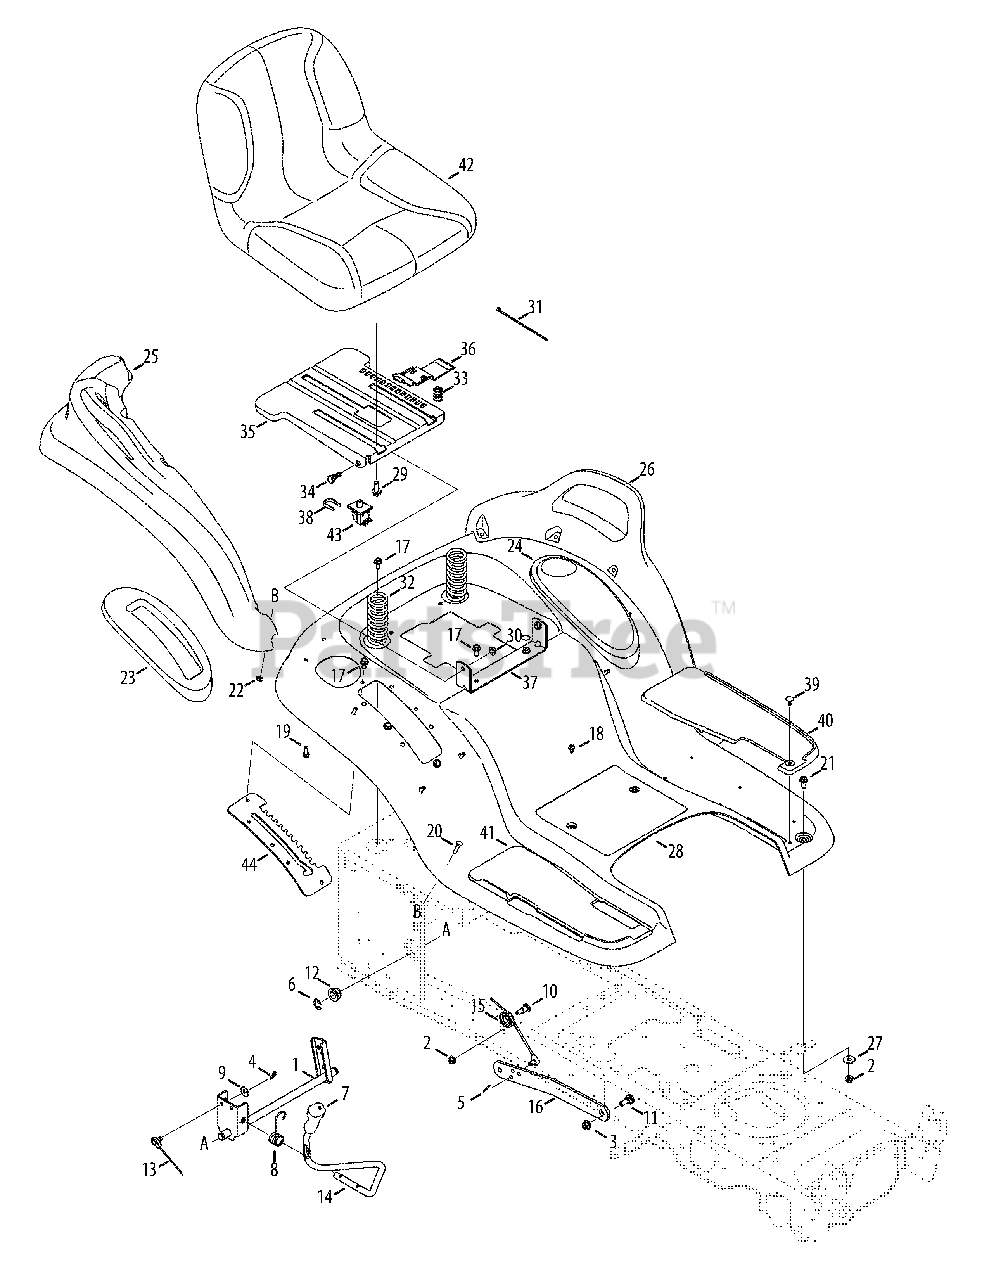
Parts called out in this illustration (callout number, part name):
1	Lift Shaft Assembly
2	Flangelock Nut, 5/16-18
3	Flangelock Nut, 3/8-16
4	Cotter Pin, .072 DIA. x 1.13 LG
5	Bow-Tie Cotter Pin
6	E-Ring, .625 DIA. SHAFT
7	Handle Grip
8	Torsion Spring
9	Spring Washer, .401 x .870 x .063
10	Shoulder Screw, .437 x .470:5/16-18
11	Shoulder Bolt, .500 x .270:3/8-16
12	Hex Flange Bearing
13	Lift Cable, 16.16 LG
14	Lift Handle
15	Pulley Roller Cable
17	Taptite Screw, Lock Washer, 5/16-18:.750
18	Taptite Screw, Lock Washer, 1/4-20
19	Hi-Lo Screw, Lock Washer, 1/4-15
20	Carriage Screw, 1/4-20:1.00
21	Taptite Screw, 5/16-18:.750
22	Sems Nut, 1/4-20
23	Lift Lever Cover
24	Cover with Cup Holder
25	RH Fender Flare
26	LH Fender Flare
27	Flat Washer, .344 x 1.00 x .063 HDN
29	Hex Head Flange, 3/8-16:.875
30	Flangelock Nut, 5/16-18
31	Cable Tie, 3/16 x .05 x 7.4
32	Compression Spring, 1.71 x 3.735 x .238
33	Compression Spring, .68 x 1.065 x .055
34	Shoulder Screw, .437 x .268:5/16-18
35	Seat Mounting Bracket
36	Seat Adjustment Lever
37	Seat Pivot Bracket
38	Switch Retainer Clip
39	Ratchet Clip
40	LH Foot Pad
41	RH Foot Pad
42	Seat
43	Seat Switch
44	Lift Bracket
